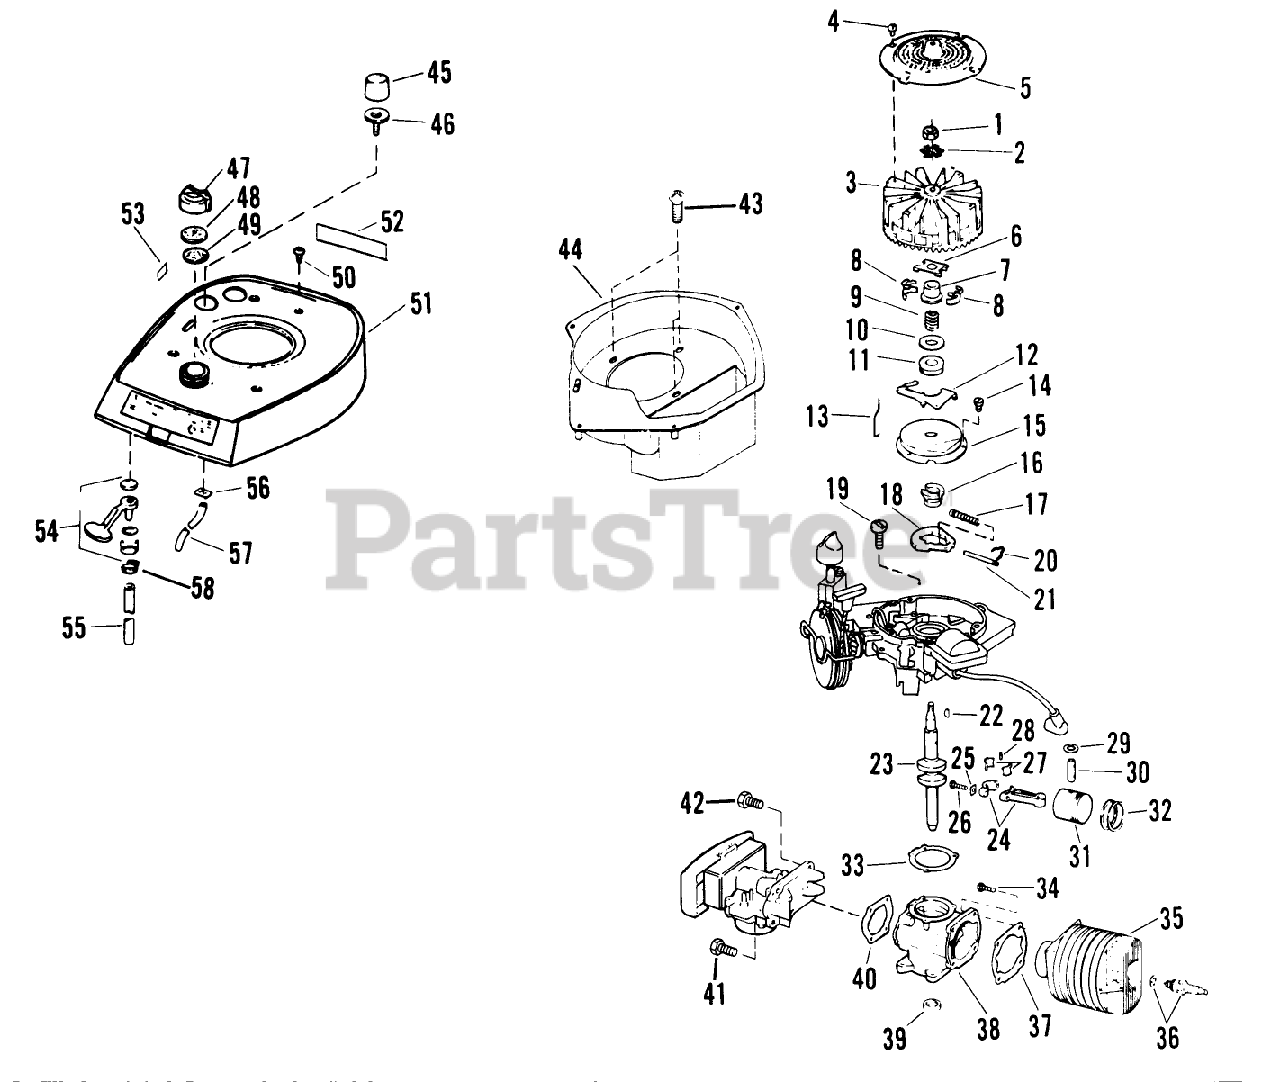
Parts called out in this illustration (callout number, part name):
4	SCREW F
7	COLLAR S
11	THRUST COLLAR S
12	LEVER-GOVERNOR S
14	SCREW S
15	DUST COVER S
16	SPARK ADV. S
17	Spring-Spark Advance
18	FLYWEIGHT S
20	SPARK ADJ. SPRING
21	PIN,SPARK ADV. S
27	LINER ASM
29	RING-RETAINING
33	GASKET S
36	Spark Plug Gasket
37	GASKET S
40	GASKET S
41	SCREW S
42	SCREW S
43	Screw-Air Baffle
45	P-BULB LAV-RUB
48	BAFFLE - FOAM SM
49	GASKET S
50	SCREW S
56	LOCKNUT S
